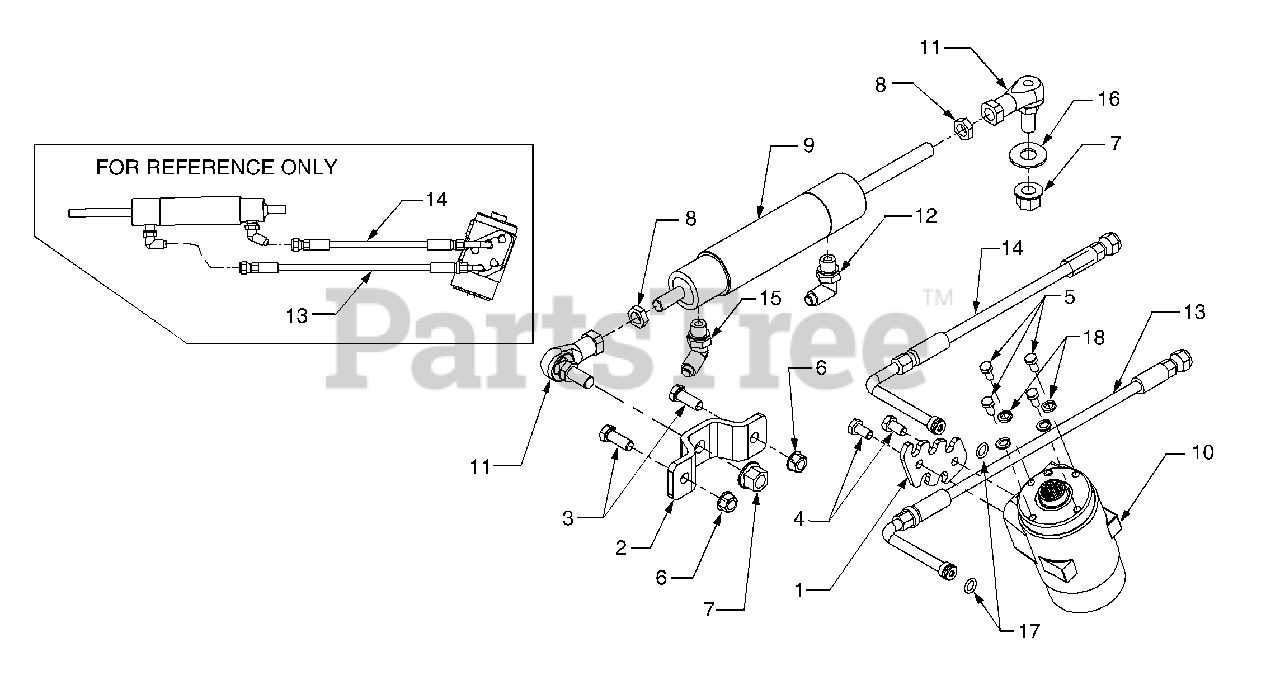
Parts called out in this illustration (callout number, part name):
1	Plate, Steering Pump Port
2	Bracket, Cylinder Mounting
3	Screw, Hex Cap 3/8-16 x 1.0 GR5
4	Screw, Hex Cap M8-1.25 x 16MM GR5
5	Screw, Hex Cap, M6 x 14MM
6	Nut, Hex Flange Lock, 3/8-16
7	Nut, Hex Flange Lock, M12 x 1.75
8	Nut, Hex, M12 x 1.75 RH
9	Cylinder, Steering
10	Pump, Hydraulic Steering
11	Ball Joint, 12MM x 1.75 RH
12	Fitting, 90 Degree Elbow
13	Hose, Front Steering
14	Hose, Rear Steering
15	Fitting, 45 Degree
16	Washer, Flat, .51 x 1.12 x .060
17	O-Ring, .426 x .566 x .070
18	Washer, Lock, 1/4"
